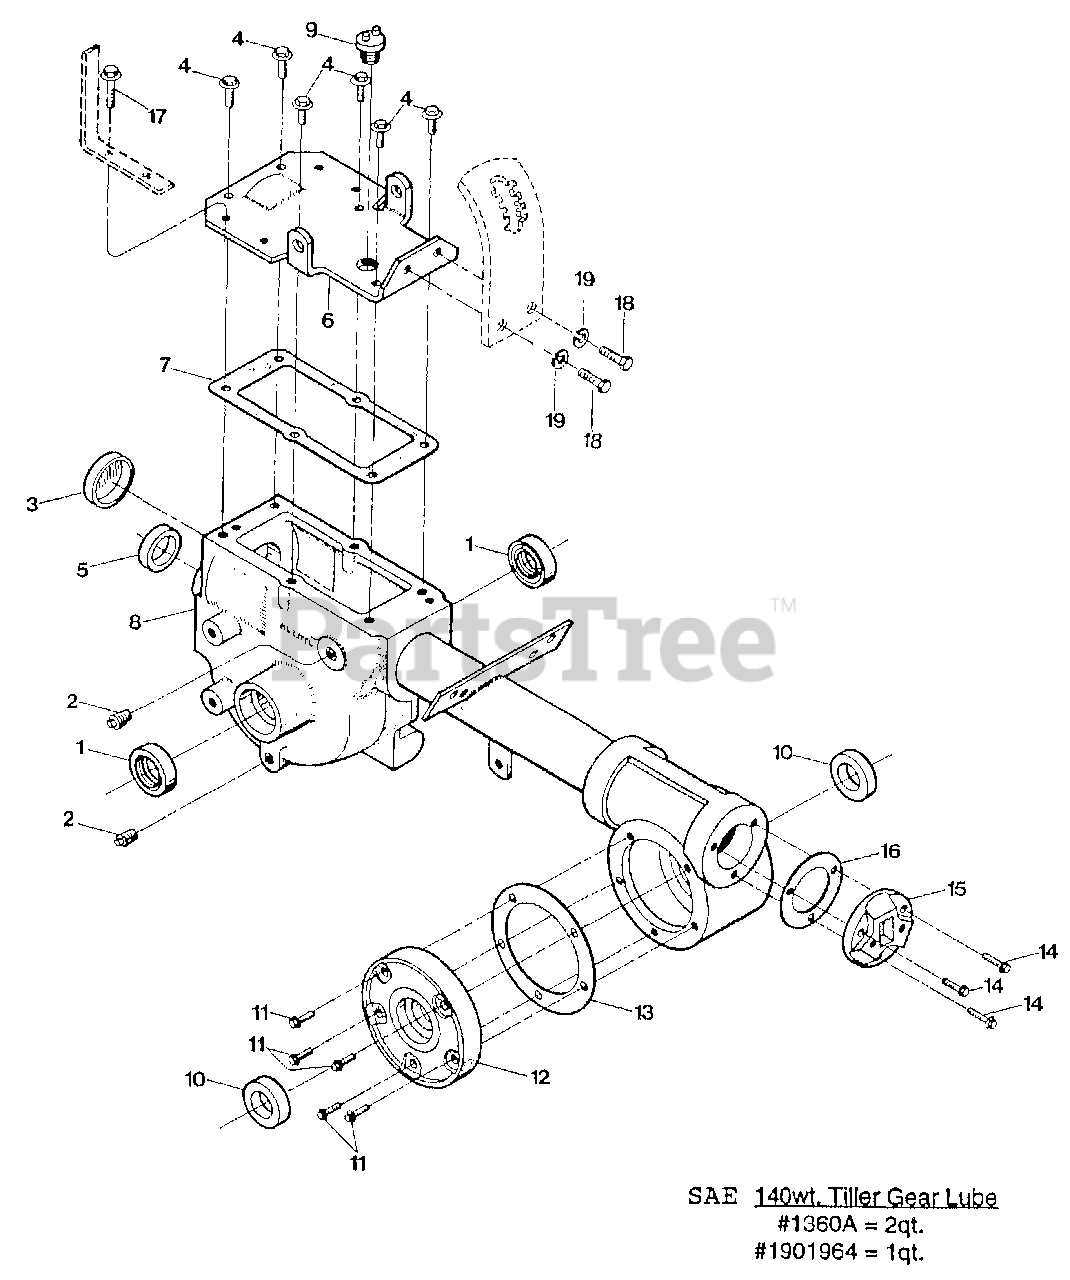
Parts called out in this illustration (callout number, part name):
1	SEAL-OIL WHEELSHAFT
2	PLUG-PIPE 1/4 NPT
3	SEAL-BORE
4	SCR-HFLK 5/16-18X.75 ZP
5	SEAL-PINION SHAFT PT/85030/00
6	KIT-COVER TRANS W/HDW
7	GASKET-TRANS COVER
8	ASSM-TRANS A-UNIT JR W/UP
9	PLUG-OIL FILL 3/4-10
10	SEAL-TILLER SHAFT
11	SCR-HXSKT 1/4-20X.625
12	COVER-TILLER HSG MACH
13	GASKET-TILLER COVER (FITS ALL COVERS)
14	SCR-HFLK 1/4-20X.87
15	CAP-REAR #1115
16	GASKET-BRG COVER
17	SCR-HFLK 5/16-18X1.00 ZP
18	SCR-HH 3/8-16X.75 G5 ZP
19	WASHER-LK .375 @ DEPL
